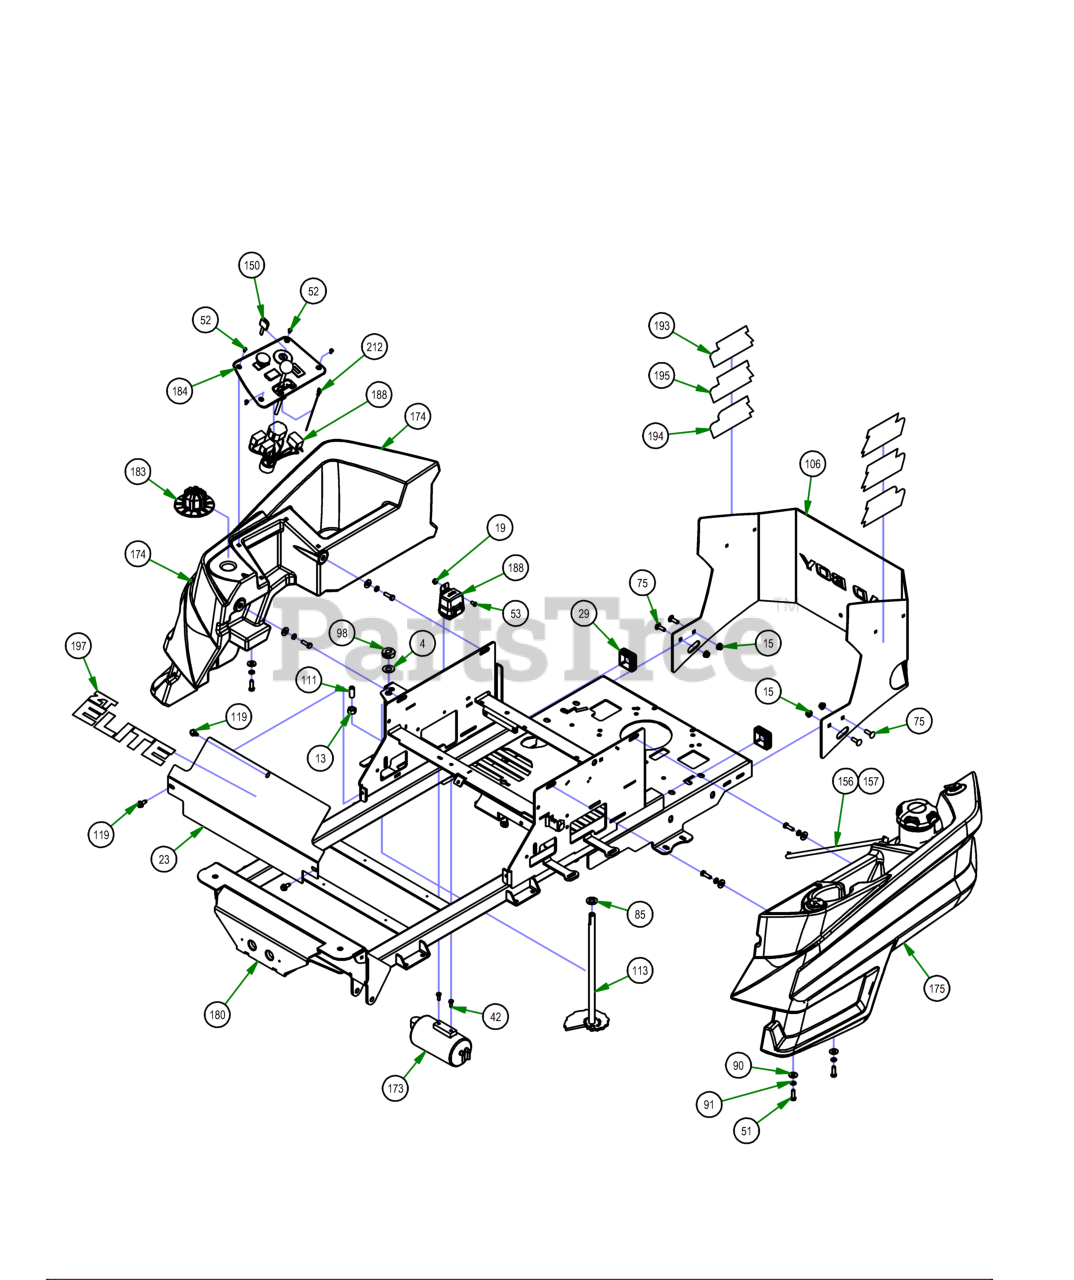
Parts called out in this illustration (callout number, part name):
4	.625 ID x 1.250 OD x .062 THK F/W Nylon
13	1/2-13 HEX NUT ZINC
15	5/16-18 NYLON INSERT FLANGE LOCKNUT ZINC
19	1/4-20 HEX SERRATED FLANGE NUT HARD/ZINC
23	2021 ZT Cooler Cover Painted
29	2X2 Frame Plug
42	M6-1.0 X 16MM DIN 933 HEX TAP BOLT (CL 8.8) ZINC
51	5/16-18 X 1 HEX CAP SCREW (GR.5) ZINC
52	10-32 X 3/8 BUTTON SOCKET CAP SCREW 18-8 STAINLESS STEEL
53	1/4-20 X 1/2 BUTTON SOCKET CAP SCREW 18-8 STAINLESS STEEL
75	5/16-18 X 1 CARRIAGE BOLT (GR.8) ZINC
85	.635 ID X 1.120 OD X .140 THICK FLAT WASHER NYLON
90	5/16 USS FLAT WASHER (7/8 OD) ZINC
91	5/16 SPLIT LOCKWASHER ZINC
98	5/8" Split Collar
106	2021 ZT Rear Plate - Painted
111	Dial Rod Plunger
113	ZT Deck Height Bar Assembly
119	5/16-18 X 3/4 HEX WASHER SLOT (F) TCS ZINC
150	Ignition Key
156	15" Fuel Line Assembly
157	37" Fuel Line Assembly
173	ZT/Mav EPA Cannister Assy
174	2021 Maverick Right Side Tank
175	2021 Maverick Left Side Tank
180	2021 ZT Frame - Painted
183	MZ/ZT Deck Height Dial
184	2019 ZT/Maverick Control Panel Assembly
188	Wiring Harness
193	2021 ZT Elite 747cc Back Plate Cluster
194	2021 ZT Elite 726cc Back Plate Cluster
195	2021 ZT Elite 725cc Back Plate Cluster
197	2017 ZT Elite Cooler Cover Decal
212	2017 MZ/ZT/MAV Tach Wire Assy
